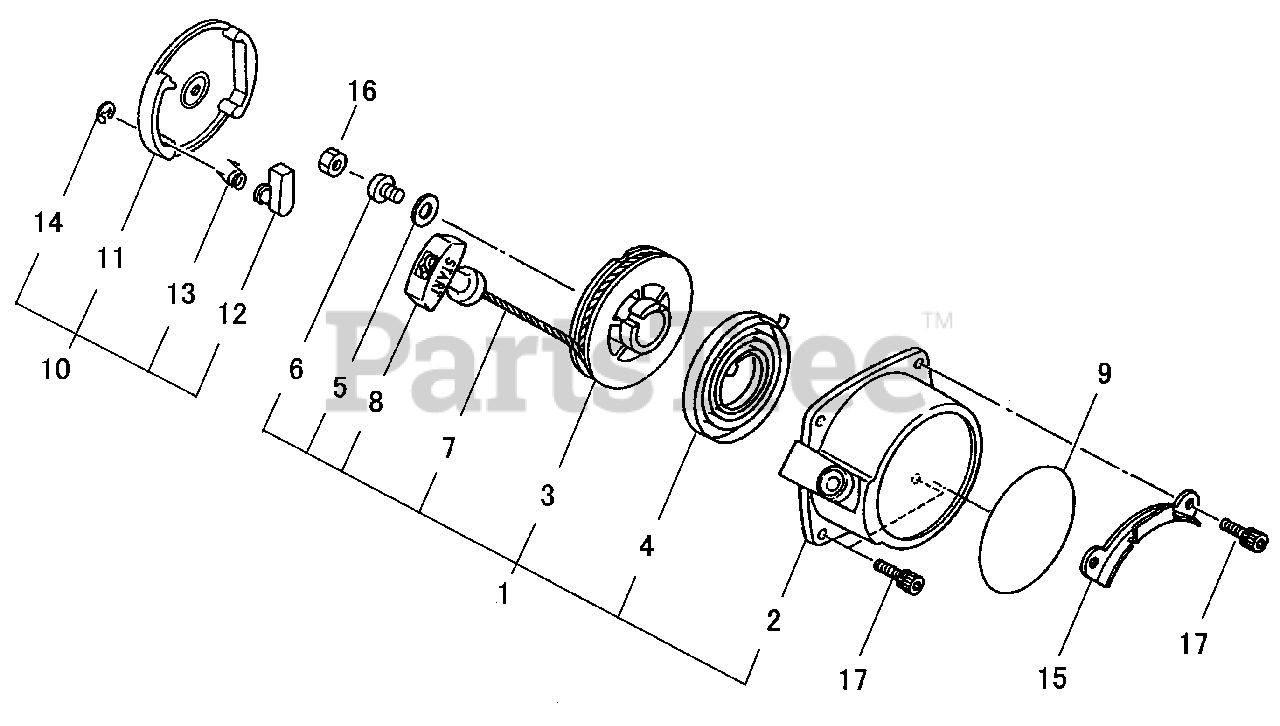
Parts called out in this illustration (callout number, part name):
1	STARTER ASSY
2	CASE, STARTER
3	REEL, ROPE
4	SPRING, REWIND
5	WASHER - 5
6	SCREW - 5
7	ROPE, STARTER
8	GRIP, STARTER
9	LABEL - TRADE
10	STARTER PAWL ASSY
11	PAWL, STARTER
12	PAWL, STARTER
13	SPRING, RETURN
14	RING, RETAINING
15	BRACKET
16	NUT
17	SCREW - 4X16
